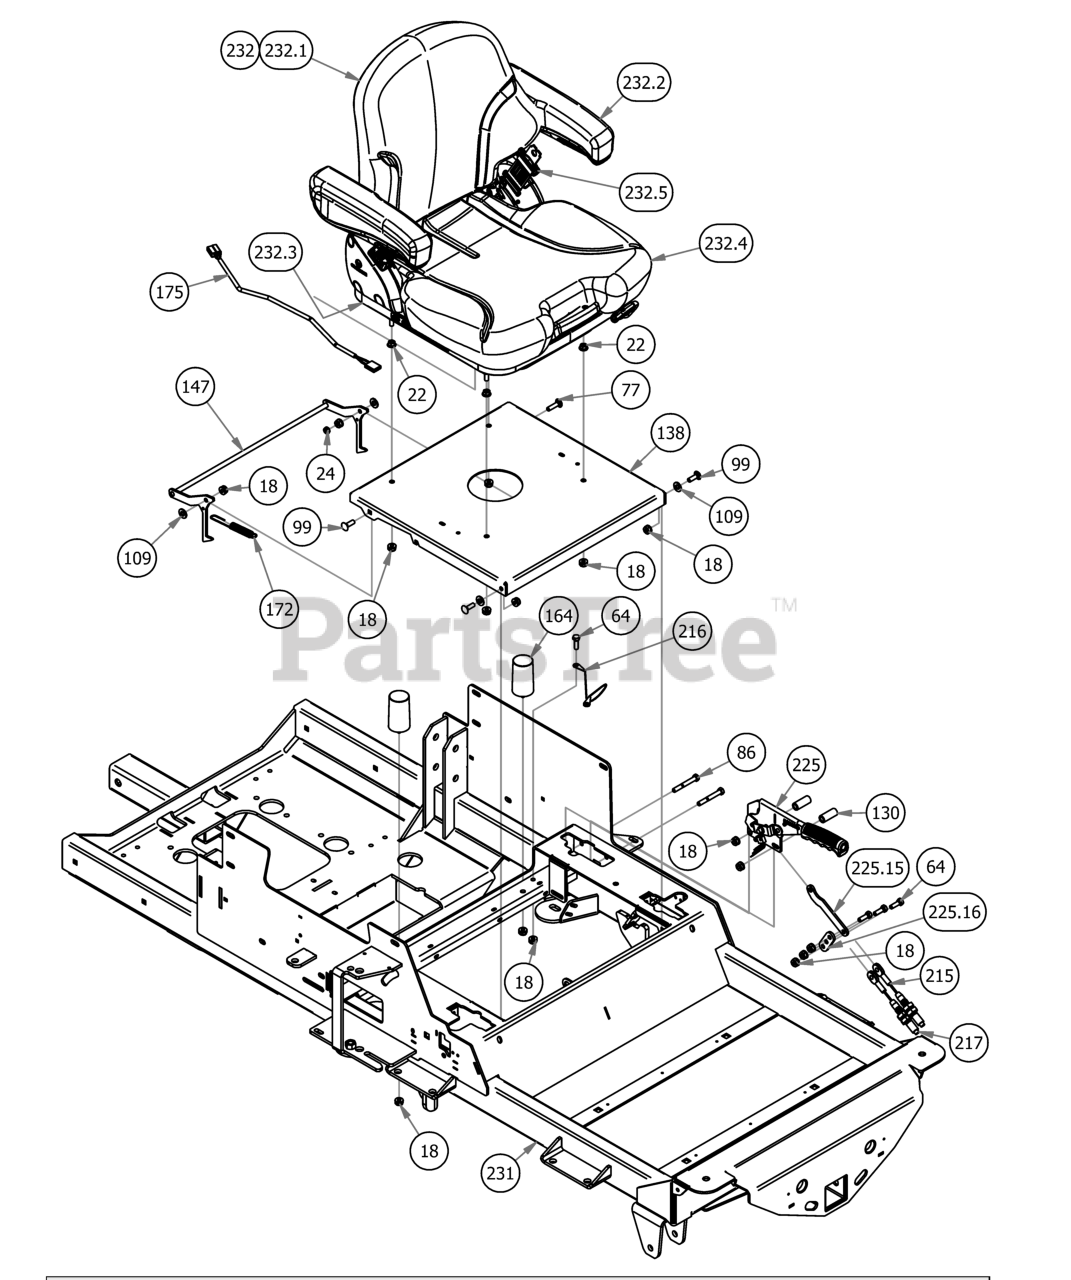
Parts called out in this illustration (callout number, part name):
18	5/16-18 Nylon Flange Nut
22	5/16" Flange Nut
24	5/16-18 Nylock Jam Nut 1/2 Nut
64	5/16" x 1" Bolt
77	5/16" x 1 1/4" Carriage Bolt
86	5/16" x 2 1/2" Bolt
99	5/16" x 1" Carriage Bolt
109	.360 ID Plastic Washer
130	2019 Outlaw Brake Handle Spacer .625 x 1.5
138	2019 Outlaw Seat Plate
147	Seat Latch Rod Assembly
164	2019 Bad Boy X Cylindrical Seat Mount
172	Brake Spring
175	Seat Switch Adapter
215	2019 Short Brake Cable-Suspension Models
216	Seat Cable
217	2019 Long Brake Cable-Renegade, Rogue
225	2019 Brake Handle Assembly
225.15	2019 Brake Load Balancer - Upper Tab
225.16	2019 Brake Load Balancer - Lower Tab
231	2019 Horizontal Diesel Frame
232	2019 Renegade Seat
232.1	Backrest Cushion
232.2	Arm Rest Kit
232.3	Slave & Adjuster
232.4	Seat Cushion
232.6	Seat Switch
